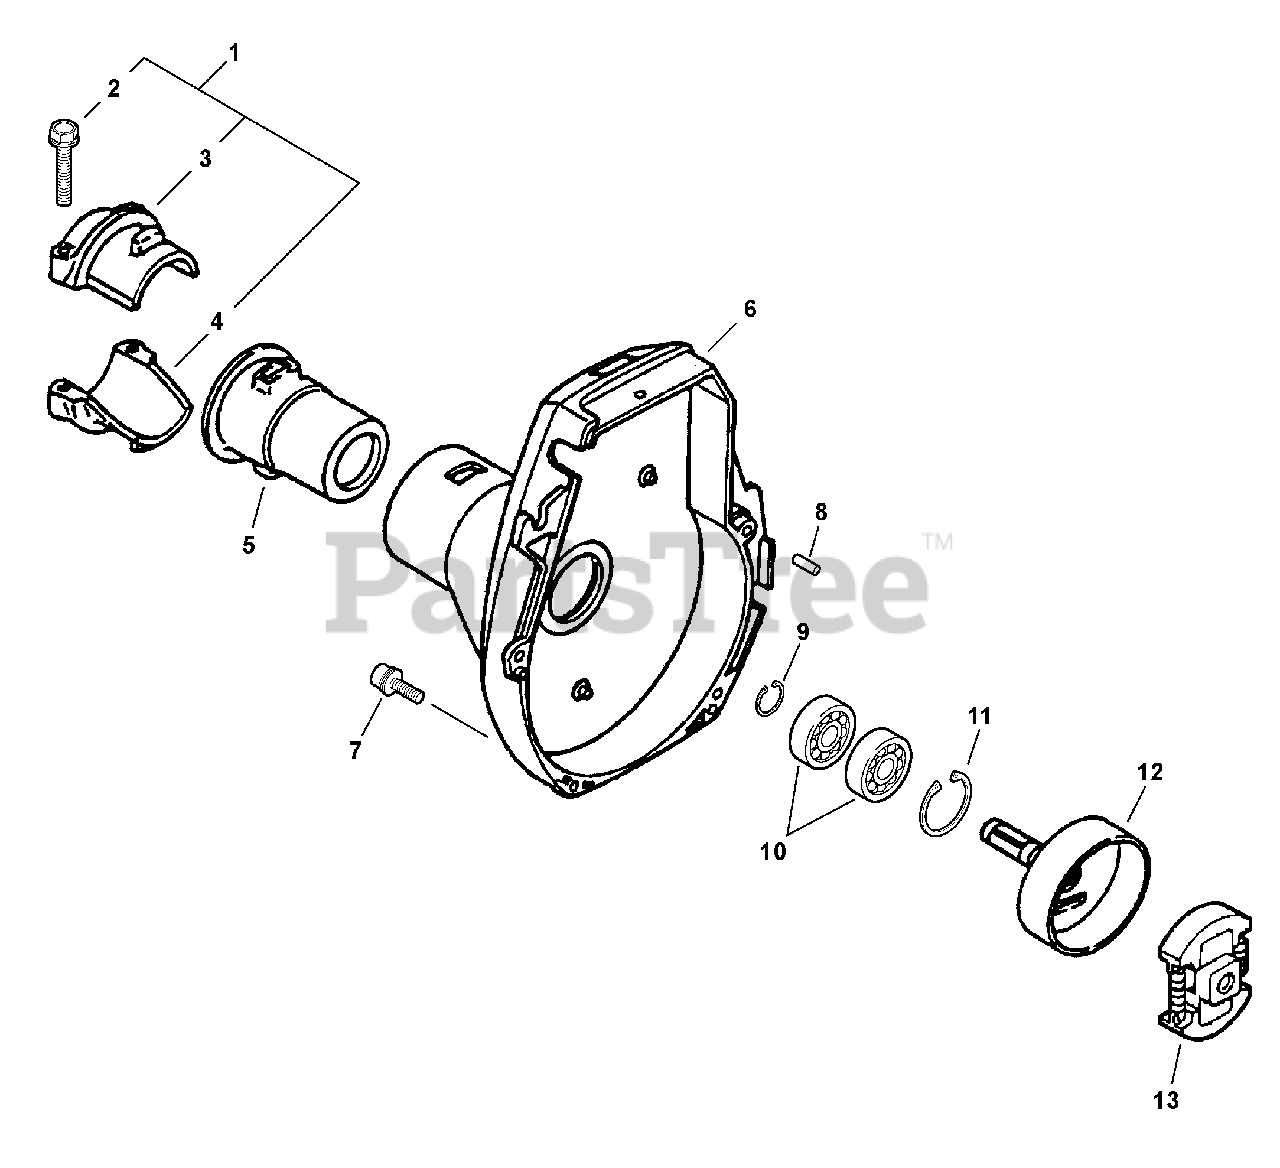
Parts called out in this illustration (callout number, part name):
1	Holder kit
2	Bolt 5x25
6	Fan Cover Asy
7	Screw 4x16
8	Dowel pin
9	Circlip 12
10	Bearing, Ball - 6001
11	Circlip 28
12	Drum, clutch
13	Clutch Asy
